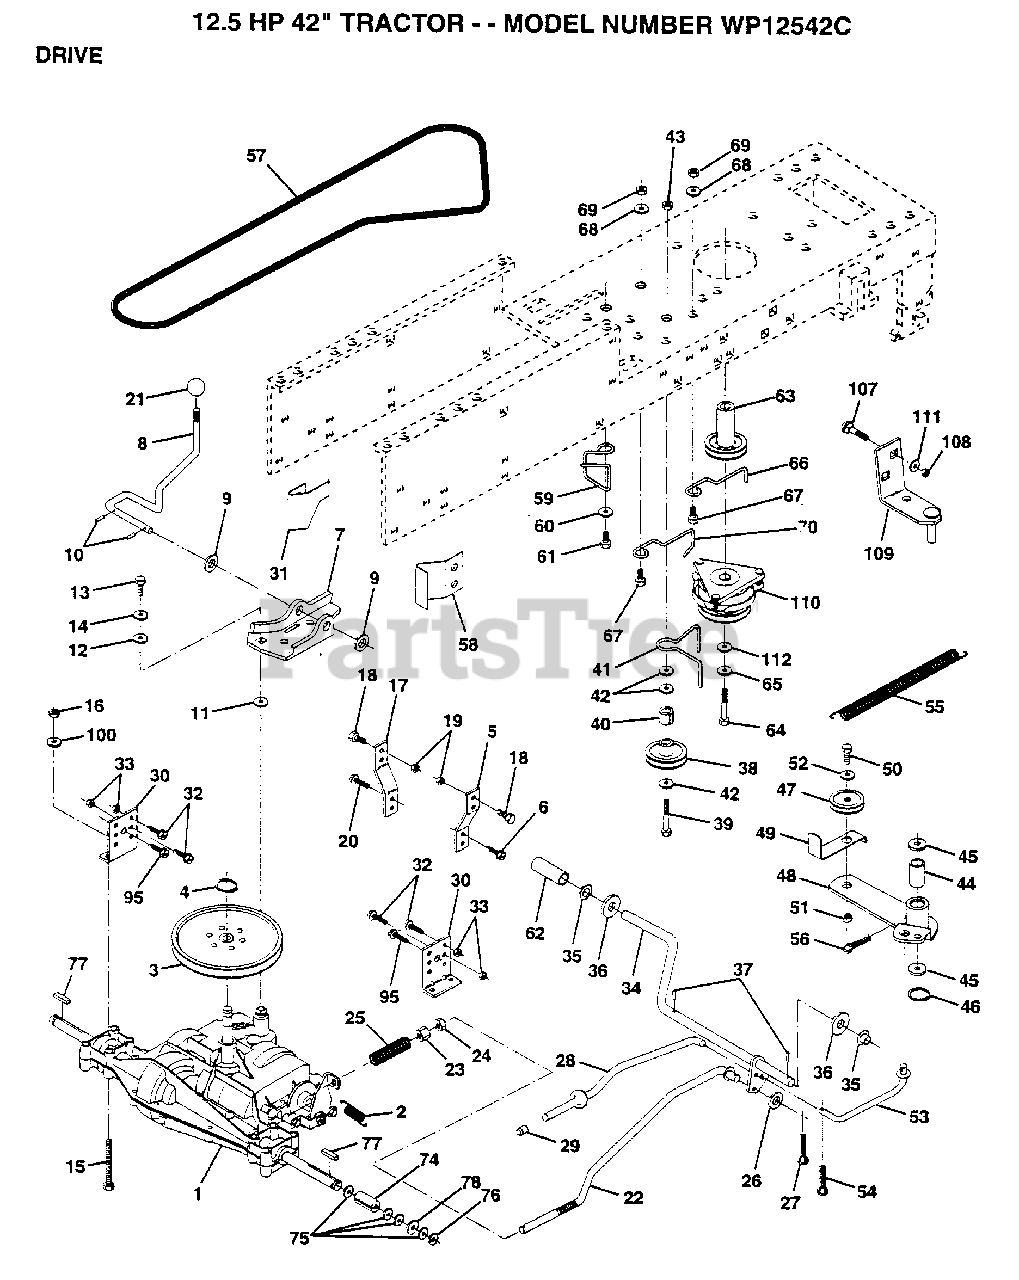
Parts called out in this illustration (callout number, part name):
3	PULLEY TRANS
5	STRAP TORQUE
6	SCREW
8	SHIFT ROD
9	WASHER
10	PIN COTTER 1/8
11	WASH-SHFT PLT LT
12	WASHER LT
14	LOCKWASHER
15	BOLT HEX
17	STRAP TORQUE
18	BOLT
19	NUT
20	SCREW
21	KNOB T (1/2-HOLE)
22	BRAKE ROD
23	NUT
24	NUT
25	SPRING ROD LT
26	WASHER
27	COTTER PIN
28	BRAKE PARK ROD
29	PLUNGER CAP T
30	TRANSAXLE MTG BKT
31	"KEEPER,BELT LH T"
32	BOLT
33	NUT
35	NYLON BEARING
36	WASHER LT
38	PULLEY.IDLER.FLAT
39	BOLT
40	SPACER T
41	BELT KEEPER LT
42	WASHER
44	"LY, BEARING"
45	WASHER LT
46	KLIP RING
48	ARM IDLER
49	RETAIN BELT
52	WASHER
53	"LINK, CLUTCH T"
54	COTTER PIN
55	"SPRING, RETURN LT"
56	COTTER PIN
58	"KEEPER,BELT RH T"
59	KEEPER BELT CNTSP
60	WASHER
61	SCREW
62	PEDAL COVER T
63	PULLEY CLU ELEC
65	LOCKWASHER
66	KEEPER.BELT.ENG.L
67	BOLT
68	WASHER
70	"KEEPER,BLT ENG LT"
71	BOLT
72	WASHER
74	SPACER LT
75	WASHER
76	E-RING LT
77	SQUARE KEY
78	WASHER
95	SCREW
100	WASHER M
107	BOLT
109	BRACKET.ASM.MTG
111	WASHER T
112	WASHER
